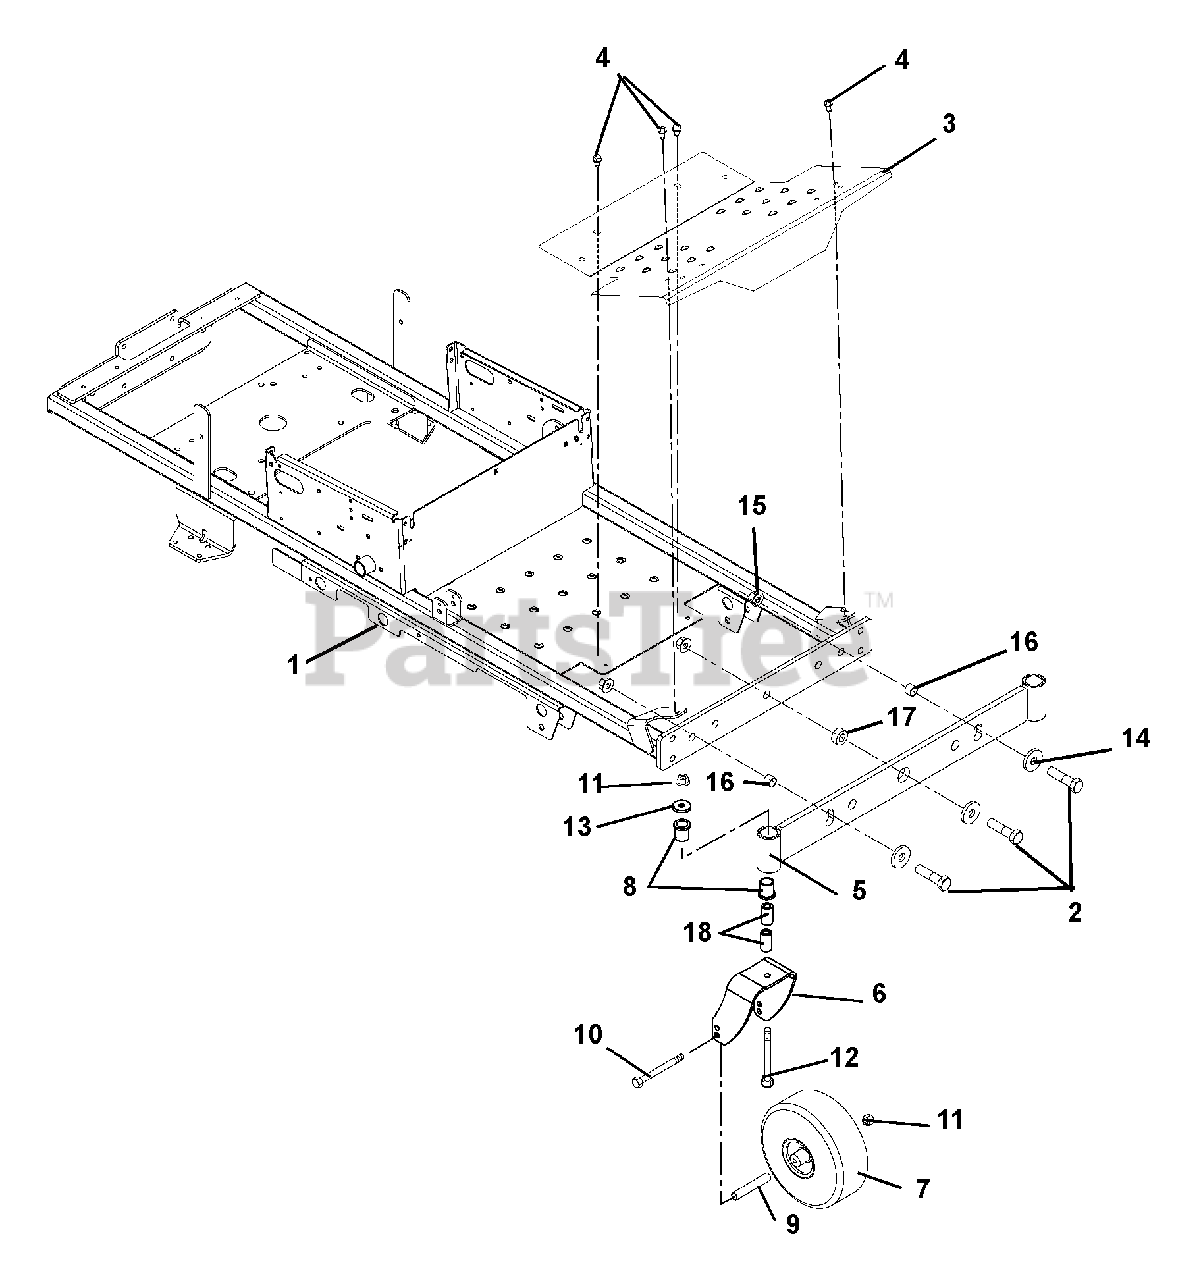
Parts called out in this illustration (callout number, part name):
1	Weldment, Frame HVZ
2	Bolt, Hex .62-11 x 2.25 Grade 8
3	Footrest, MZ
4	Screw, Tapping .31-18 x .50
5	Weldment, Front Axle
6	Fork, Caster
7	Wheel/Tire 11 x 4.00-5
7	Tire, 11.0 x 4.0 x 5.0, Monitor
8	Bushing, Flange 1.00 x 1.25 x 1.50 x 1.50
9	Spacer, Wheel
10	Bolt, Hex .50-13 x 6.50 Grade 5
11	Nut, .50-13 Nyloc Flange
12	Bolt, Hex .50-13 x 5.00 Grade 5
13	Washer, Flat Steel .511 x 1.441 x .125
14	Washer,Flat .640 x 1.81 x .250
15	Nut, Nyloc Flange .62-11
16	Spacer, .750 D x .558 Long
17	Bushing, Axle Pivot
18	Spacer, Caster
